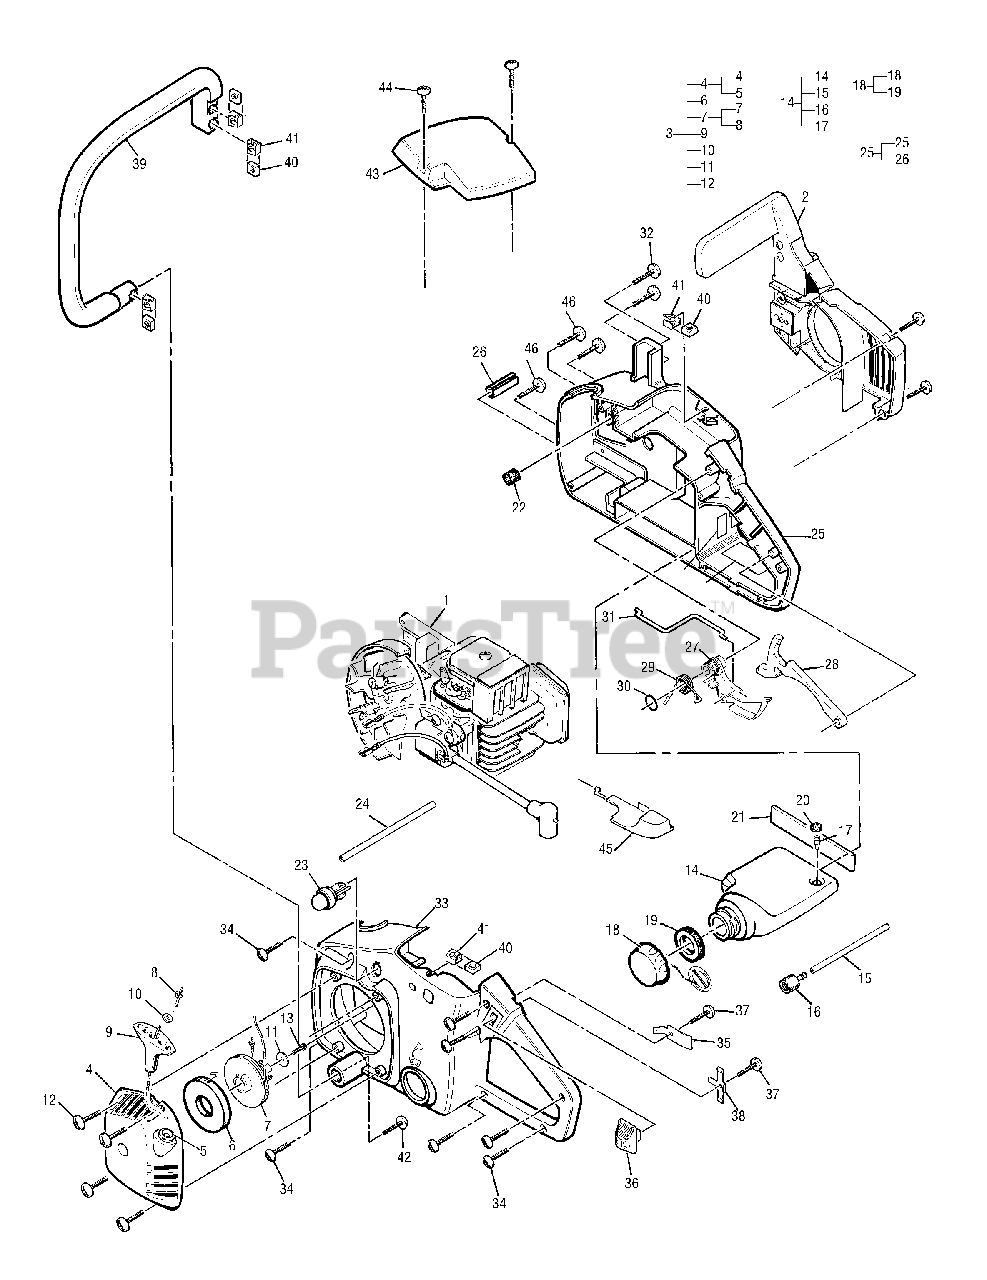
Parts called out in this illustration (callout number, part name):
1	Powerhead Asy
2	Chain Brake Asy
3	Starter Housing Asy, Yellow
4	Housing/Rope Guide Asy, Yellow
5	Rope Guide
6	Spring, Starter Rewind
7	Rope/Drum Asy (32cc)
8	Rope, Starter 50"
9	Handle, Starter
10	Bushing, Starter
11	Washer, .19 ID x .68 OD
12	Screw, 8-16 x .75 Torx Hd Plast
13	Screw, 8-16 x .75 Torx Hd Plastite
14	Oil Tank Asy
15	Hose, Oil Pick-up
16	Pickup, Oil
17	Valve, Duckbill
18	Oil Cap Asy
19	Gasket
20	Filter, Foam
21	Spacer, Oil Tank
22	Filter, Foam
23	Primer, Remote
25	Housing/Pin Asy, Right
26	Pin, Roll 1/4 x 1.0 L
27	Trigger, Throttle
28	Latch, Throttle
29	Spring, Torsional
30	"O" Ring
31	Rod, Throttle
32	Screw, 10-24 x .62 Tr Hd Torx
33	Engine Housing, Left, Blk
34	Screw, 8-16 x .75 Tr Hd, Plastite
35	Contact, Ground
36	Button,Stop Switch
37	Screw, 8-16 Plastite
38	Contact, Ignition
39	Handle, Front
40	Nut, Square 10-24
41	Retainer, Nut
42	Screw, 10-24 x .75 Tr Torx
43	Cover, Air Filter
44	Screw, 10-24 x .625 Pn Hd Torx
45	Slide, Choke
46	Screw, 10-24 x .62 Tr Hd Torx
